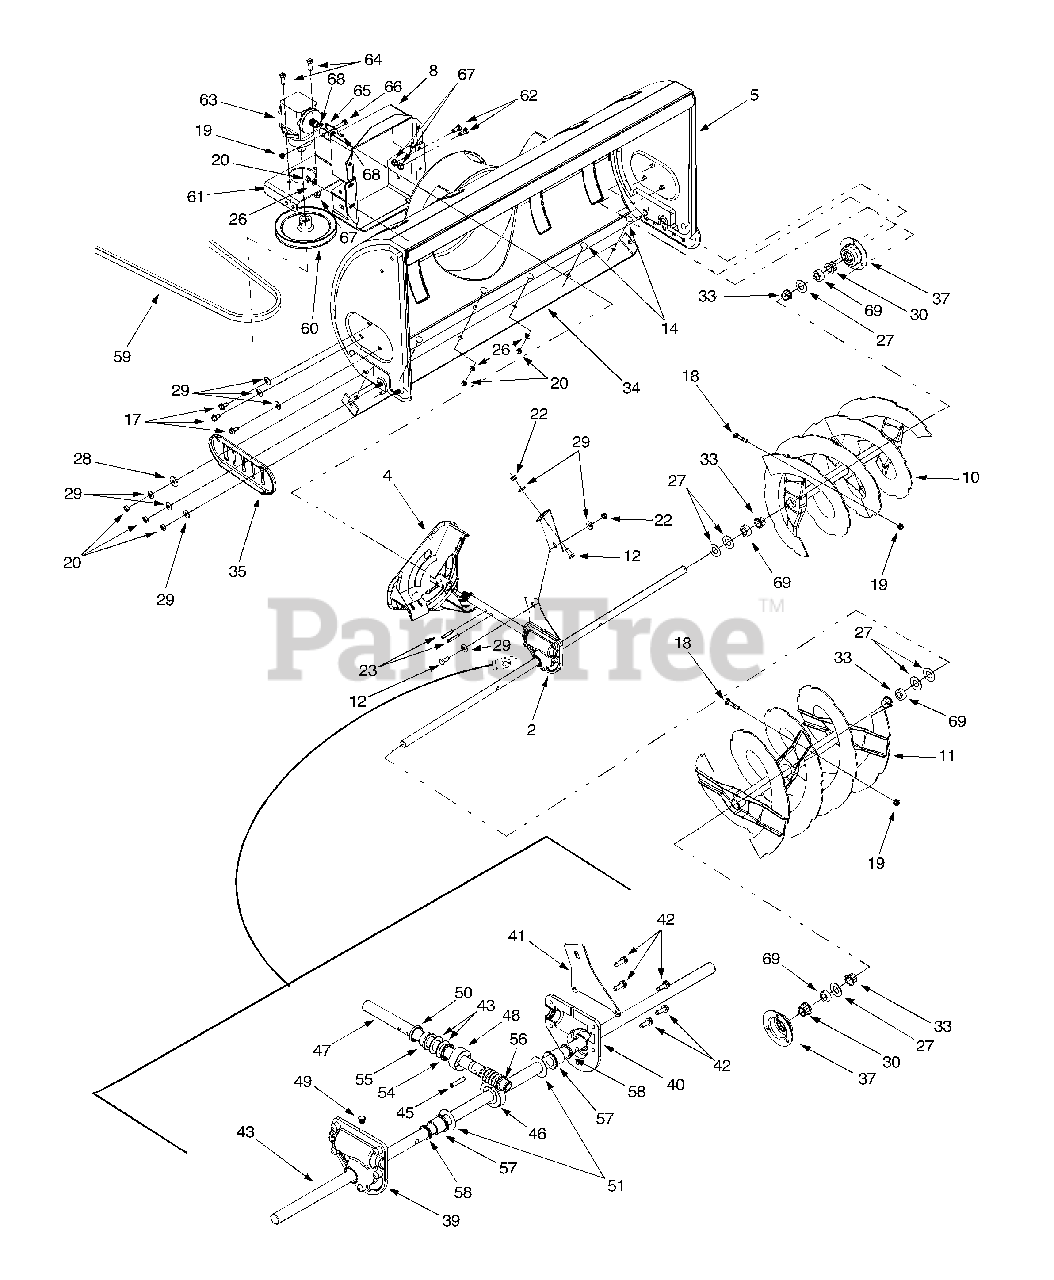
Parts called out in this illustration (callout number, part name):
2	Auger Gear Case
14	Carriage Bolt, 5/16-18 x .62
17	Self Tapping Screw, 5/16-18 x .625
18	Shear Bolt, 5/16-18 x 1.5
19	Hex Lock Nut, 5/16-18
20	Hex Nut, 5/16-18
22	Hex Nut, 5/16-24
23	Spirol Pin, 1/4 x 1-1/2
26	Lock Washer, 5/16
27	Flat Washer, .76 x 1.49 x .06
28	Flat Washer, .344 x 1.125 x .12
29	Bell Washer, .340 x .872
30	Hex Flange Bearing, .75 ID
33	Flange Bushing, .80 x .91
39	RH Reducer Housing
40	LH Reducer Housing
42	Self Tapping Screw, 1/4-20 x .75
43	Spiral Axle, 41.5"
45	Spring Spirol Pin, .25 x 1.25
46	Worm Gear, 20-Tooth
47	Worm Shaft
48	Thrust Collar
49	Grease Plug
50	Grease Seal
51	Flat Washer, .76 x 1.5 x .030
54	Thrust Bearing, .75 x 1.25 x .078
55	Flange Bearing, .75 x 1.0 x .59
56	Flange Bearing, .503 x .75
57	Flange Bearing, .754 x 1.0 x .925
58	Grease Seal
59	Lower V-belt
60	Drive Pulley, 7"
61	Drive Mounting Bracket
62	Hex Cap Screw, 3/8-16 x .75
63	Right Angle Drive
64	Hex Cap Screw, 3/8-16 x 1.0
65	Coupling
66	Hex Cap Screw, 5/16-18 x 1.75
67	Flange Lock Nut, 3/8-16
68	Square Key, 3/16 x .75
69	Spacer, .75 x .125 x .5
